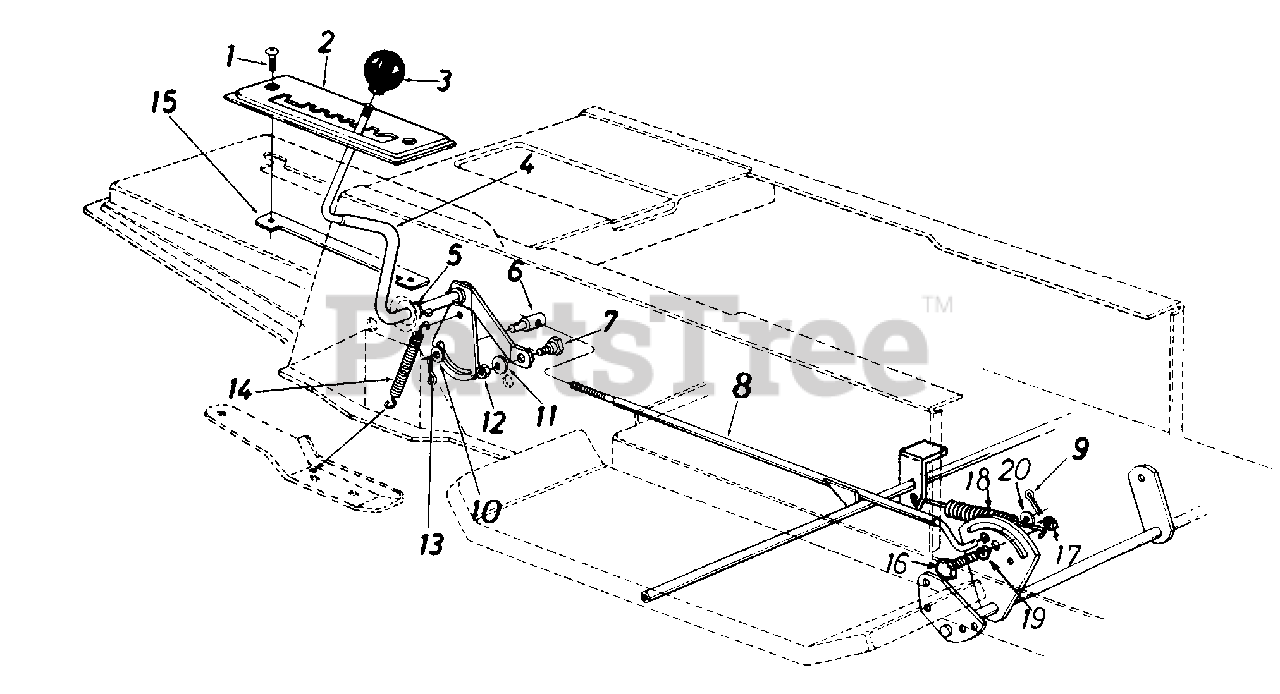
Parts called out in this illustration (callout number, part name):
1	Truss Mach. Scr. 1/4-20 x .75" Lg.
2	Speed Selector Plate 4-Speed
4	Speed Selector Cam Ass'y.
5	Flat Washer .53" I.D. x .93"
6	Ferrule 3/8-24 x .37" Dia.
7	Shoulder Bolt .435" Dia. x .160
8	Speed Control Rod Ass'y.
9	Cotter Pin 3/32" Dia. x .75"
10	Fl-Wash. .385" I.D. x .62"
11	L-Wash. 5/16" I.D.
12	Hex Nut 5/16-18 Thd.
13	Cotter Pin 3/32 Dia. x .75"
14	Spring
15	Clamping Plate
16	Hex Cap Bolt 5/16-18 x 1" Lg.
17	Hex Cent. L-Nut 5/16-18 Thd.
18	Ext. Spring .53" O.D. x 4.75" Lg.
19	Hex Nut 5/16-18 Thd.*
20	Fl-Wash. .47" I.D. x .88" O.D.
